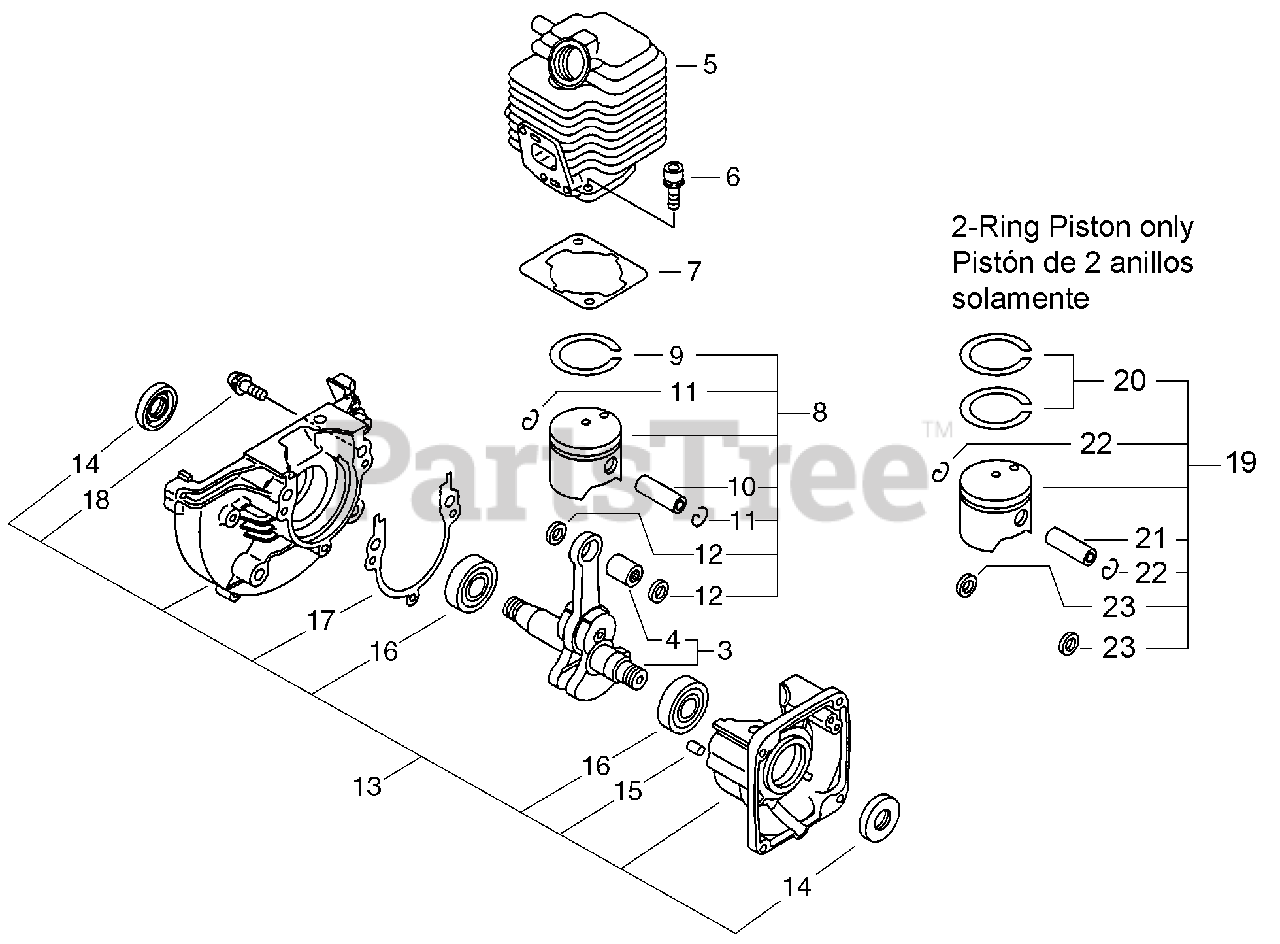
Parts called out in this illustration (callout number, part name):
3	CRANKSHAFT ASSY
4	BEARING, NEEDLE 8
5	CYLINDER
6	BOLT 5×22
7	GASKET, CYLINDER
8	PISTON KIT
9	RING, PISTON
10	PIN, PISTON 8
11	RING, SNAP
12	WASHER, THRUST
13	CRANKCASE KIT
14	SEAL, OIL 12
15	PIN, LOCATING 4
16	BEARING, BALL - 6201 C3
17	GASKET, CRANKCASE
18	BOLT 5×28
19	PISTON KIT
20	RING, PISTON
21	PIN, PISTON 8
22	RING, SNAP
23	WASHER, THRUST
